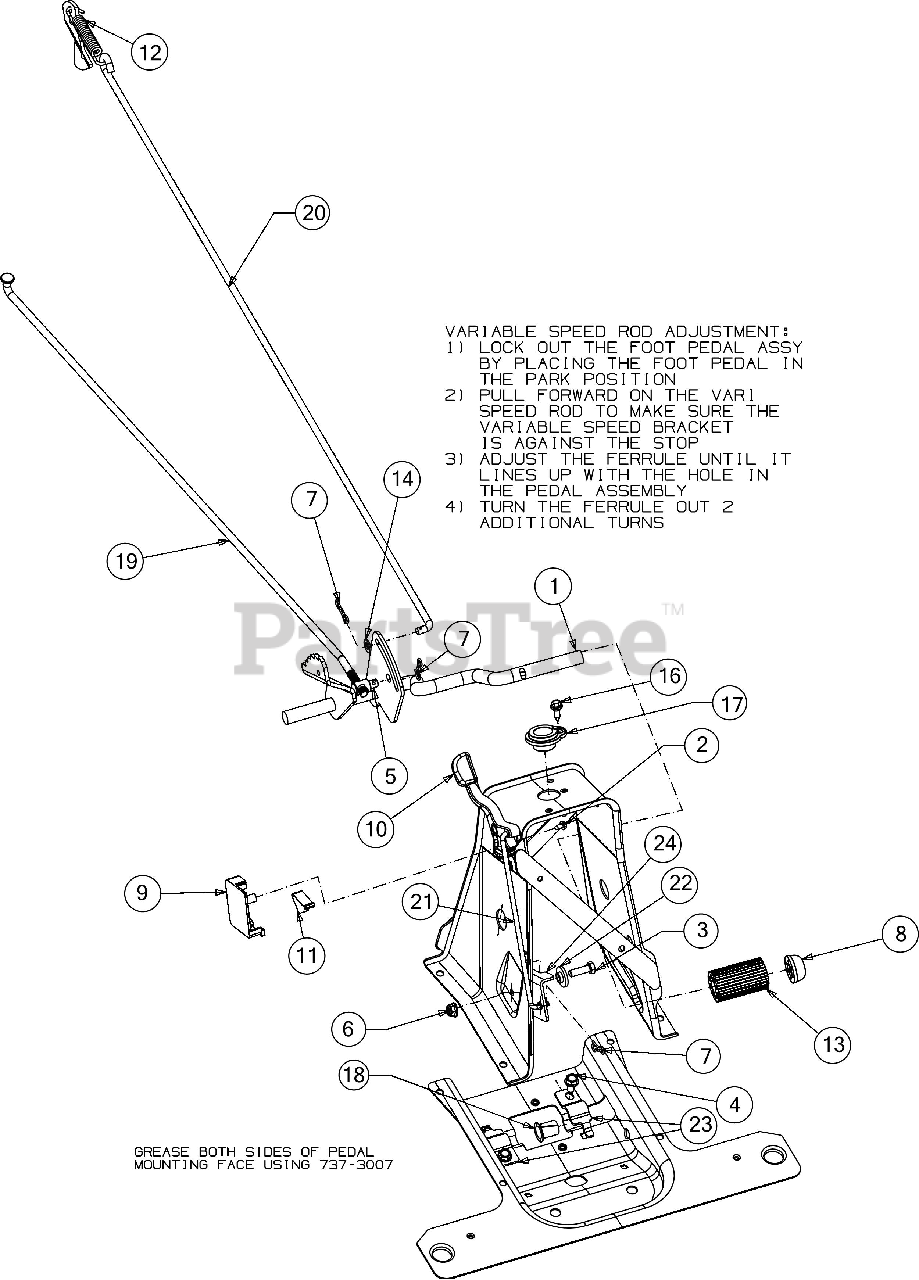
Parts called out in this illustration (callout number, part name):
1	BRAKE PEDAL ASSEMBLY
2	HEX SCREW AB-TAP #10-16 x 0.500
3	SCREW 5/16-18 x 1.0 GR5
4	SCREW 5/16-18 x .750
5	FERRULE 3/8-24 x .375
6	FLANGE LOCK NUT 5/16-18
7	BOW TIE COTTER PIN 1/4-5/16
8	PUSH CAP
9	6 SPEED CONTROL COVER
10	6 SPEED LEVER
11	SHIFT SPRING
12	EXTENSION SPRING .59 X 4.0
13	FOOT PAD 2.5 LG"
14	FLAT WASHER
16	SHOULDER SCREW
17	FLANGE BEARING
18	FLANGE BEARING .626 x .938 x .875
19	VARIABLE SPEED ROD
20	BRAKE ROD
21	SPEED SELECT ROD
22	SHOULDER SPACER
23	BRAKE SHAFT STRAP
